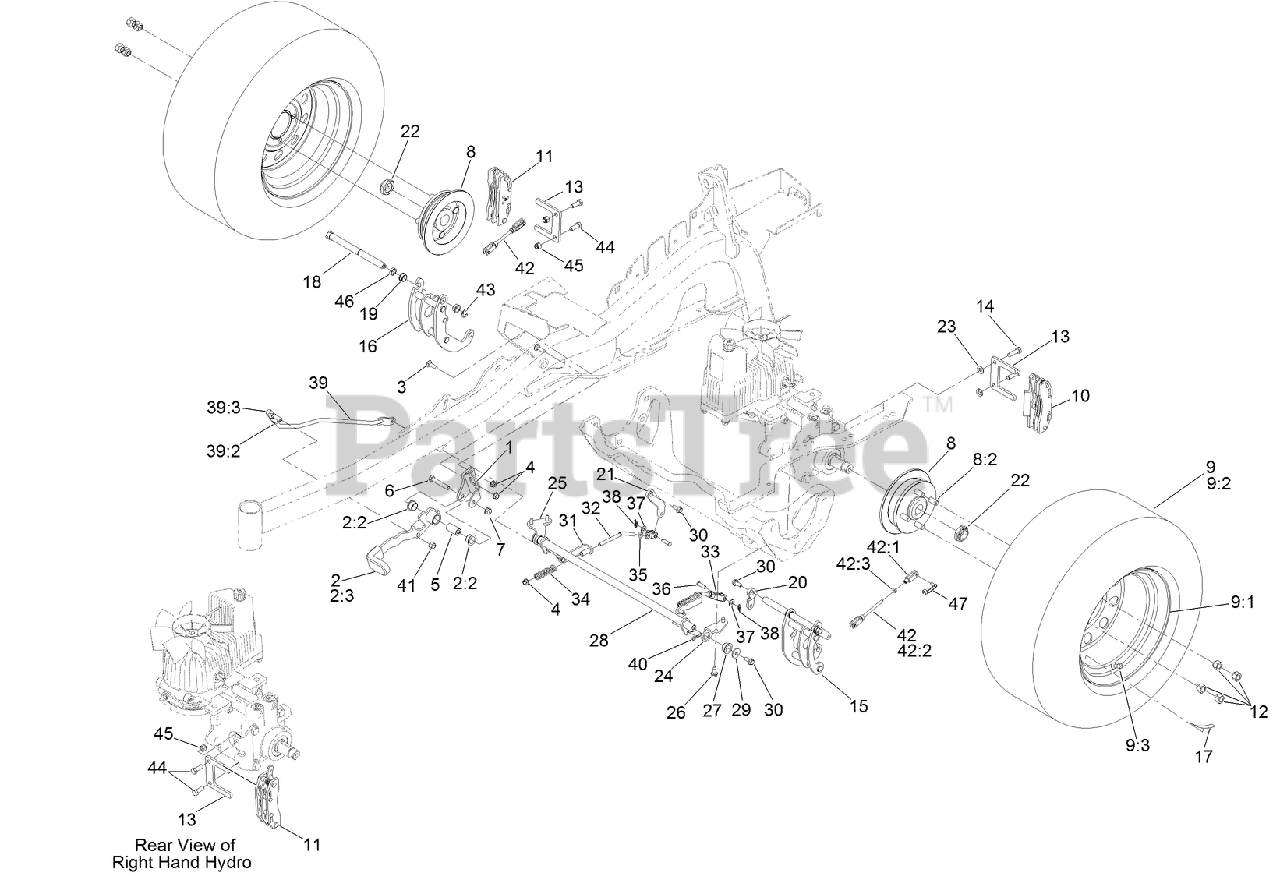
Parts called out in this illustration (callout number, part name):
1	BRACKET-MOUNT
2	BRAKE LEVER ASM W/ GRIP
2:2	BUSHING-FLANGE
2:3	GRIP-LEVER
3	BOLT-CARR
4	NUT-HF, NI
5	HANDLE-PIVOT, BRAKE
6	SCREW-HH
7	NUT-HF, NI
8	WHEEL HUB ASM
8:2	STUD-WHEEL
9	WHEEL AND TIRE ASM
9:3	STEM-VALVE
10	CALIPER-BRAKE
11	CALIPER-BRAKE, RH
12	NUT-LUG
13	PLATE-MOUNT, BRAKE
14	SCREW-LOCK, PATCH
15	MOUNT-BELLCRANK, LH
16	MOUNT-BELLCRANK, RH
17	DECAL-TORQUE, WHEEL HUB LUG
18	BELLCRANK
19	BUSHING
20	ARM-INNER, LH
21	ARM-INNER, RH
22	LOCKNUT
23	WASHER-FLAT
24	MOUNT-PIVOT, LH
25	MOUNT-PIVOT, RH
26	SCREW-HWHTF
27	BUSHING-FLANGE
28	SHAFT-CROSS
29	WASHER-FLAT
30	SCREW
31	BRACKET-L
32	LINKAGE-MID
33	YOKE-OFFSET
34	SPRING-COMPRESSION
35	NUT-JAM
36	PIN-CLEVIS
37	WASHER-PLAIN
38	PIN-COTTER, LOCKING
39	FRONT LINKAGE ASM
39:2	END-TIE ROD, RH
39:3	NUT-HJ
40	PIN-COTTER, LOCKING
41	NUT-LOCK
42	REAR LINKAGE ASM
42:1	YOKE
42:2	LINKAGE, REAR
42:3	NUT-JAM
43	E-RING
44	SCREW-HH
45	NUT-LOCK, NI
46	SPACER
47	PIN-CLEVIS, SPRING
